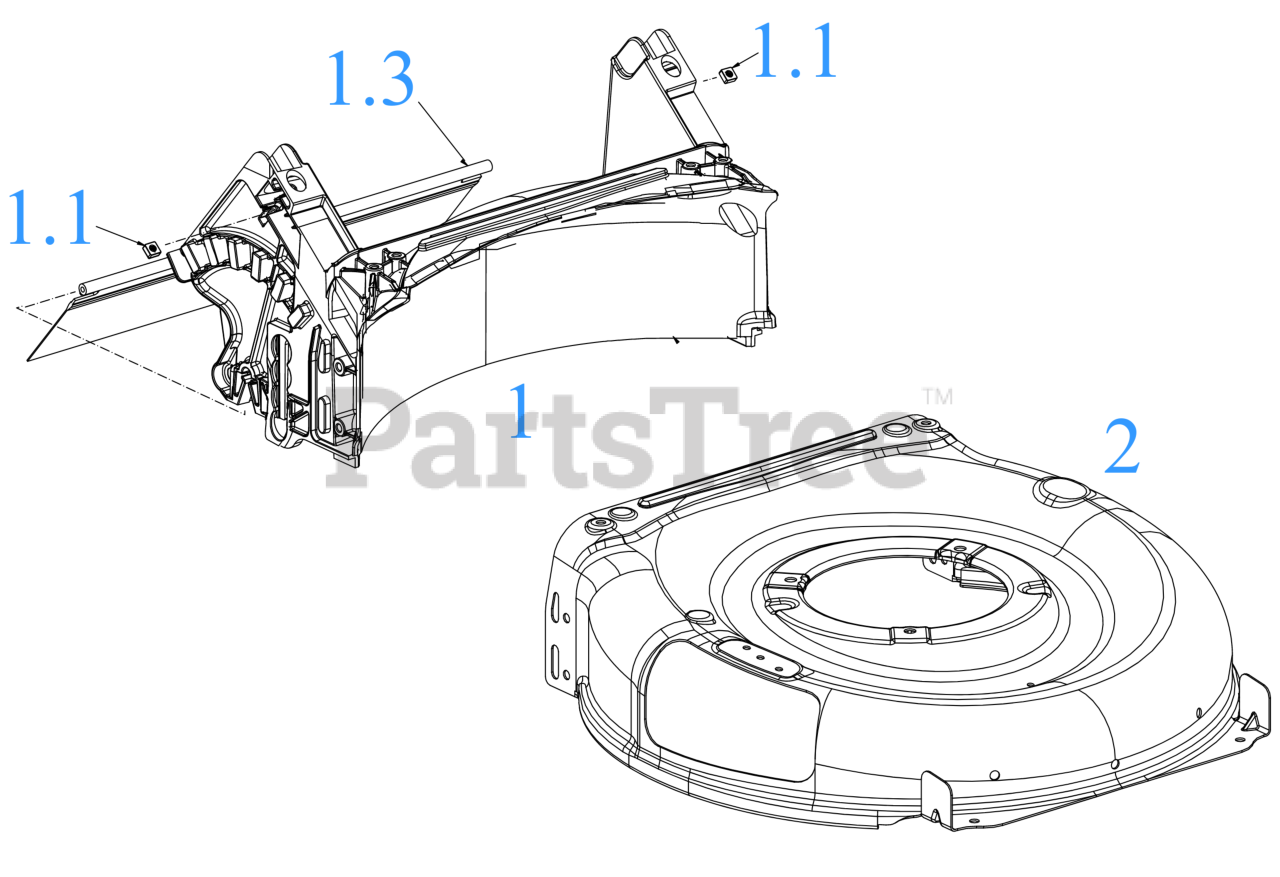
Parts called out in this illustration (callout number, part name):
1	REAR BAFFLE ASSEMBLY
1	21" REAR BAFFLE
1.1	SQUARE NUT 1/4-20
1.3	TRAILSHIELD
